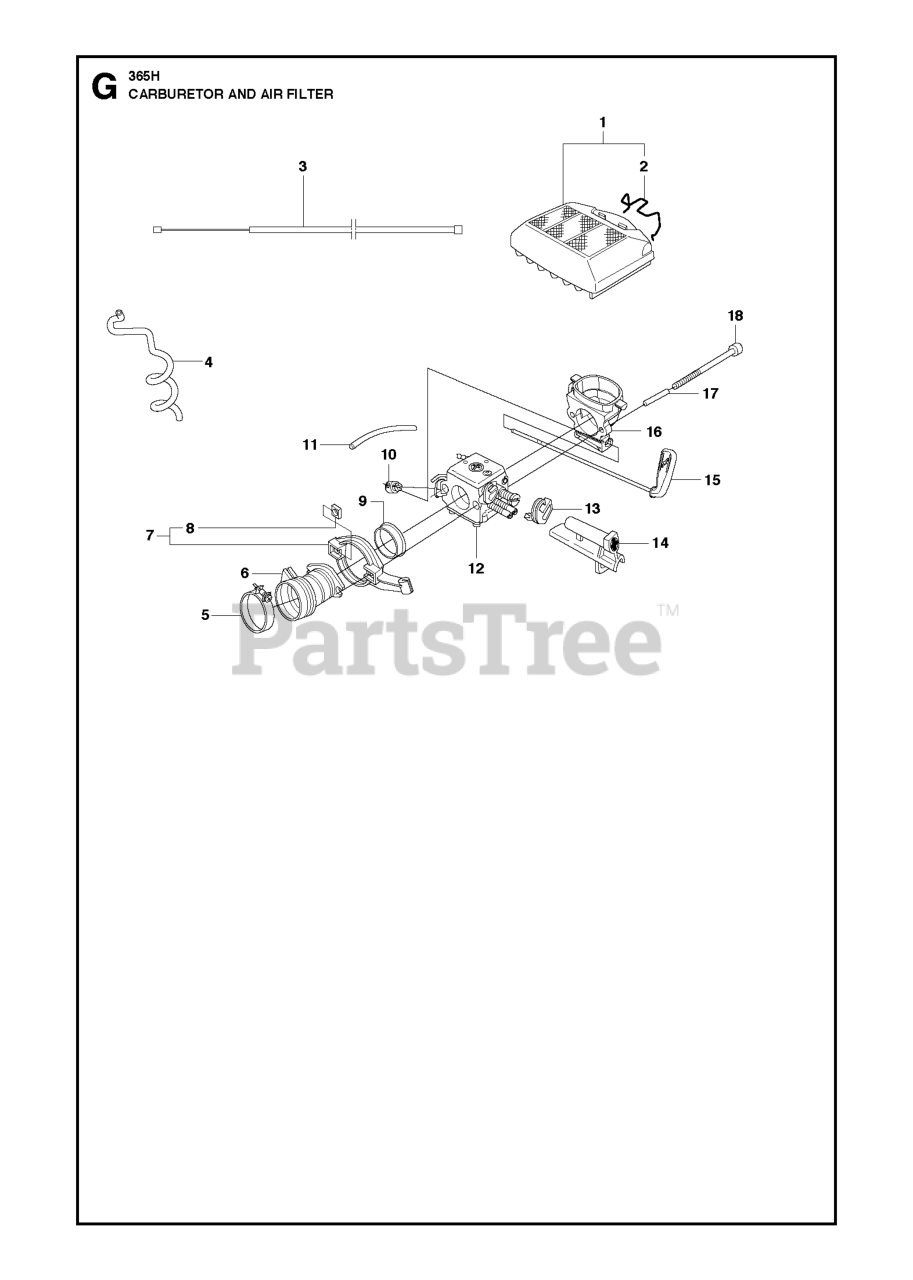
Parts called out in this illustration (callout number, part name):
1	AIR FILTER ASSY
2	AIR FILTER CLIP
3	THROTTLE WIRE ASSY
4	FUEL HOSE STRAIGHT 265
5	CLAMP
12	CARBURETOR WALBRO HD-6B
15	CHOKE CONTROL
16	FILTER HOLDER
